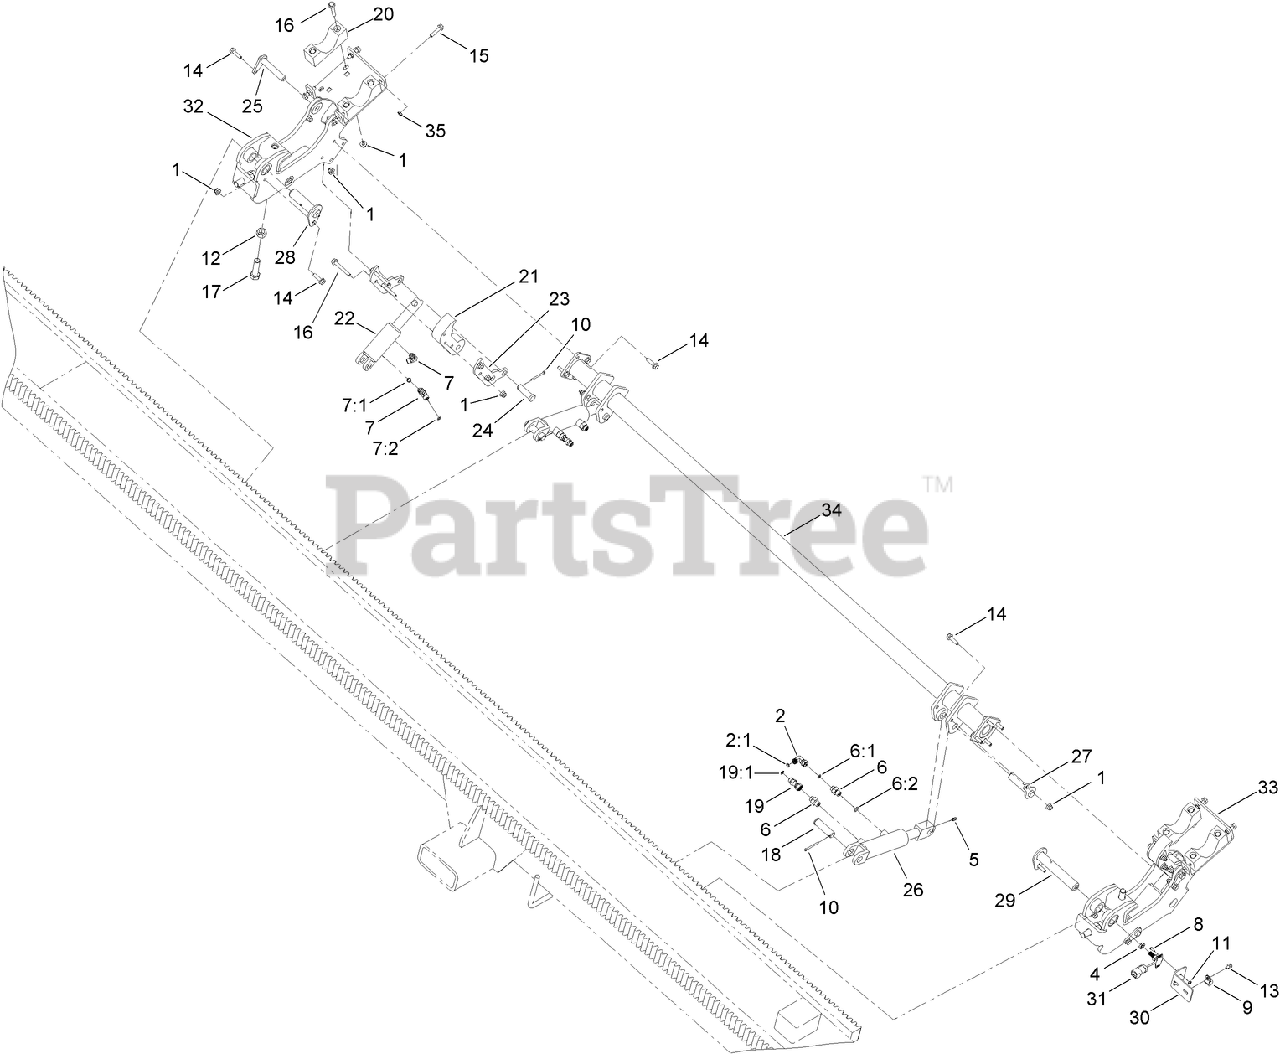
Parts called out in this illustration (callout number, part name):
1	NUT-LOCK, HHF
2	FITTING-ADAPTOR
2:1	O-RING
4	NUT-HEX
5	FITTING-GREASE
6	FITTING-STRAIGHT
6:1	O-RING
6:2	O-RING
7	FITTING-90 DEG
7:1	O-RING
7:2	O-RING
9	CLAMP-R
10	PIN-COTTER
11	NUT-HEX, KEPS
12	NUT-HEX
13	SCREW-HHF
14	SCREW-HHF
15	SCREW-HHF
16	SCREW-HHF
17	SCREW-HH
18	PIN-CLEVIS
19	FITTING-STRAIGHT
19:1	O-RING
20	HOLDER-PIPE
21	INSERT-GRIPPER
22	HYD CYLINDER ASM
24	PIN-CLEVIS
25	PIN-PIVOT (W/ FLAG)
26	CYLINDER ASM
27	PIN-PIVOT
28	PIN-PIVOT, CAM
29	PIN-PIVOT
30	PLATE-MOUNT
31	SENSOR-ROTARY
32	LOADER-ROD, REAR
33	LOADER-ROD, FRONT
35	NUT-HEX
